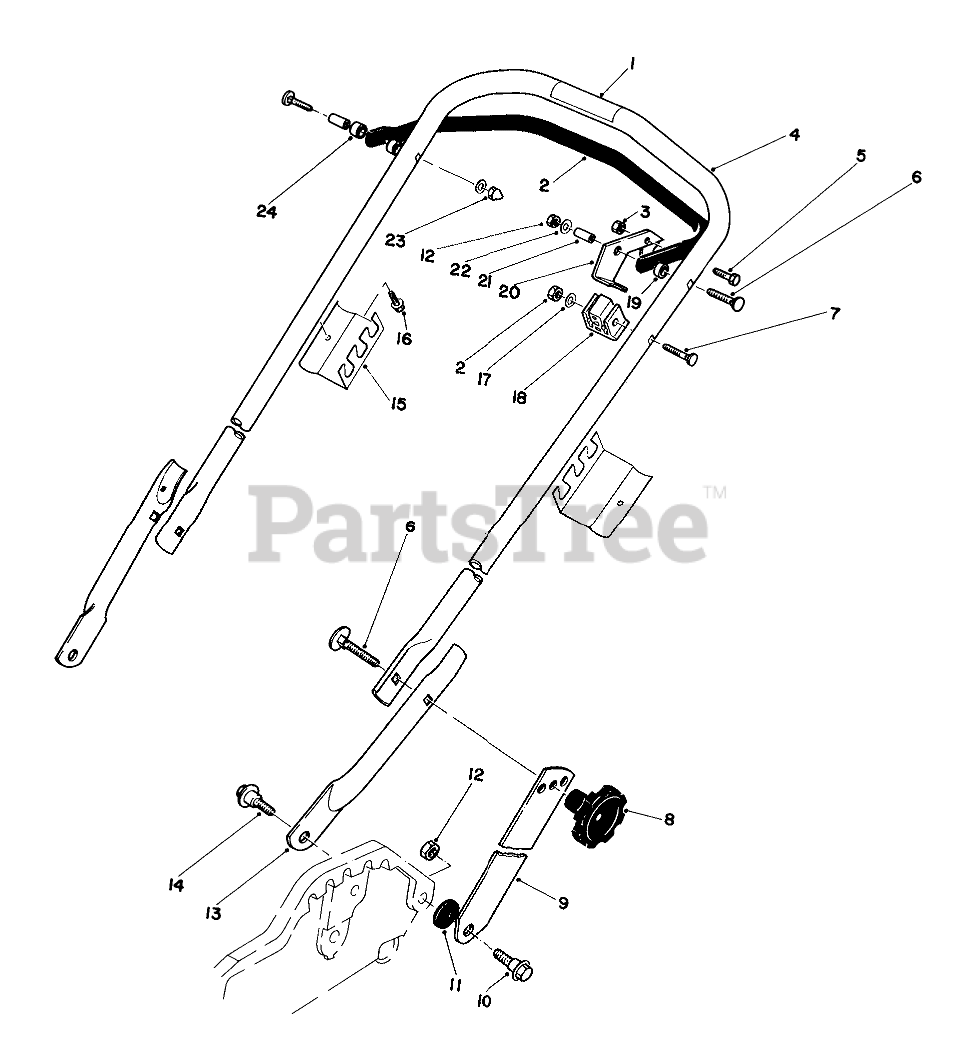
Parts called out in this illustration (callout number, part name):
1	Decal-Instructions
2	CONTROL BAR
3	NUT-LOCK, NI
4	Upper Handle (Incl. Ref. #1)
5	SCREW-HH
6	5/16-18 X 2 HNDLE SCREW
7	SCREW-HANDLE
9	Handle Latch
10	SCREW-SHOULDER
11	SPACER
12	NUT-LOCK, NI
13	Hand-Lower
14	SCREW-SHOULDER
15	Bag Support
16	SCREW-HWHTF
17	WASHER-FLAT
18	SUPPORT-CABLE
19	Nylon Spacer
20	Lever-Control
21	Spacer
22	WASHER-PLAIN
23	NUT-LOCK, CAP
24	SPACER-NYLON
